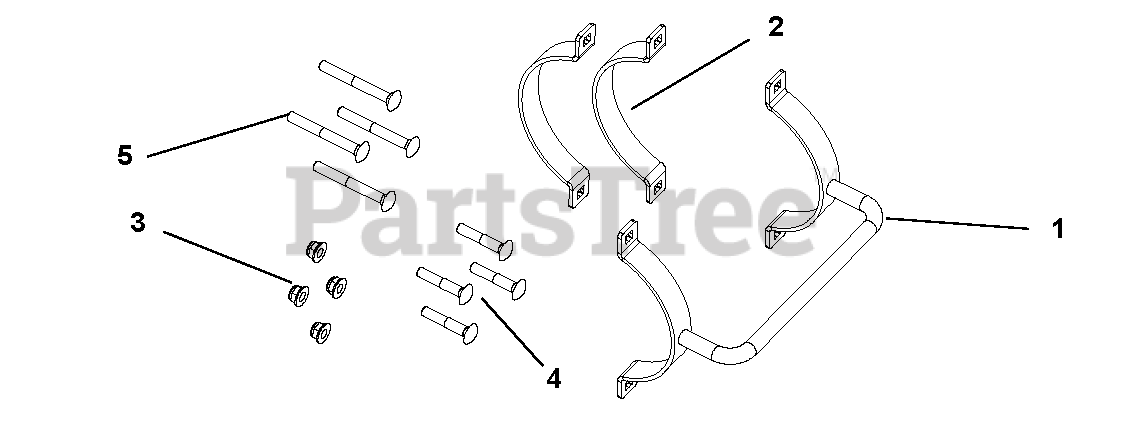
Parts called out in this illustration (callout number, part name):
1	Weldment, Hydraulic Cylinder Clamp
2	Bracket, Cylinder Clamp
3	Nut, Nyloc Flange .312-18
4	Bolt, Round Head Square Neck .312-18 x 2.75 (917004)
5	Bolt, Round Head Square Neck .312-18 x 1.75 (917003)
